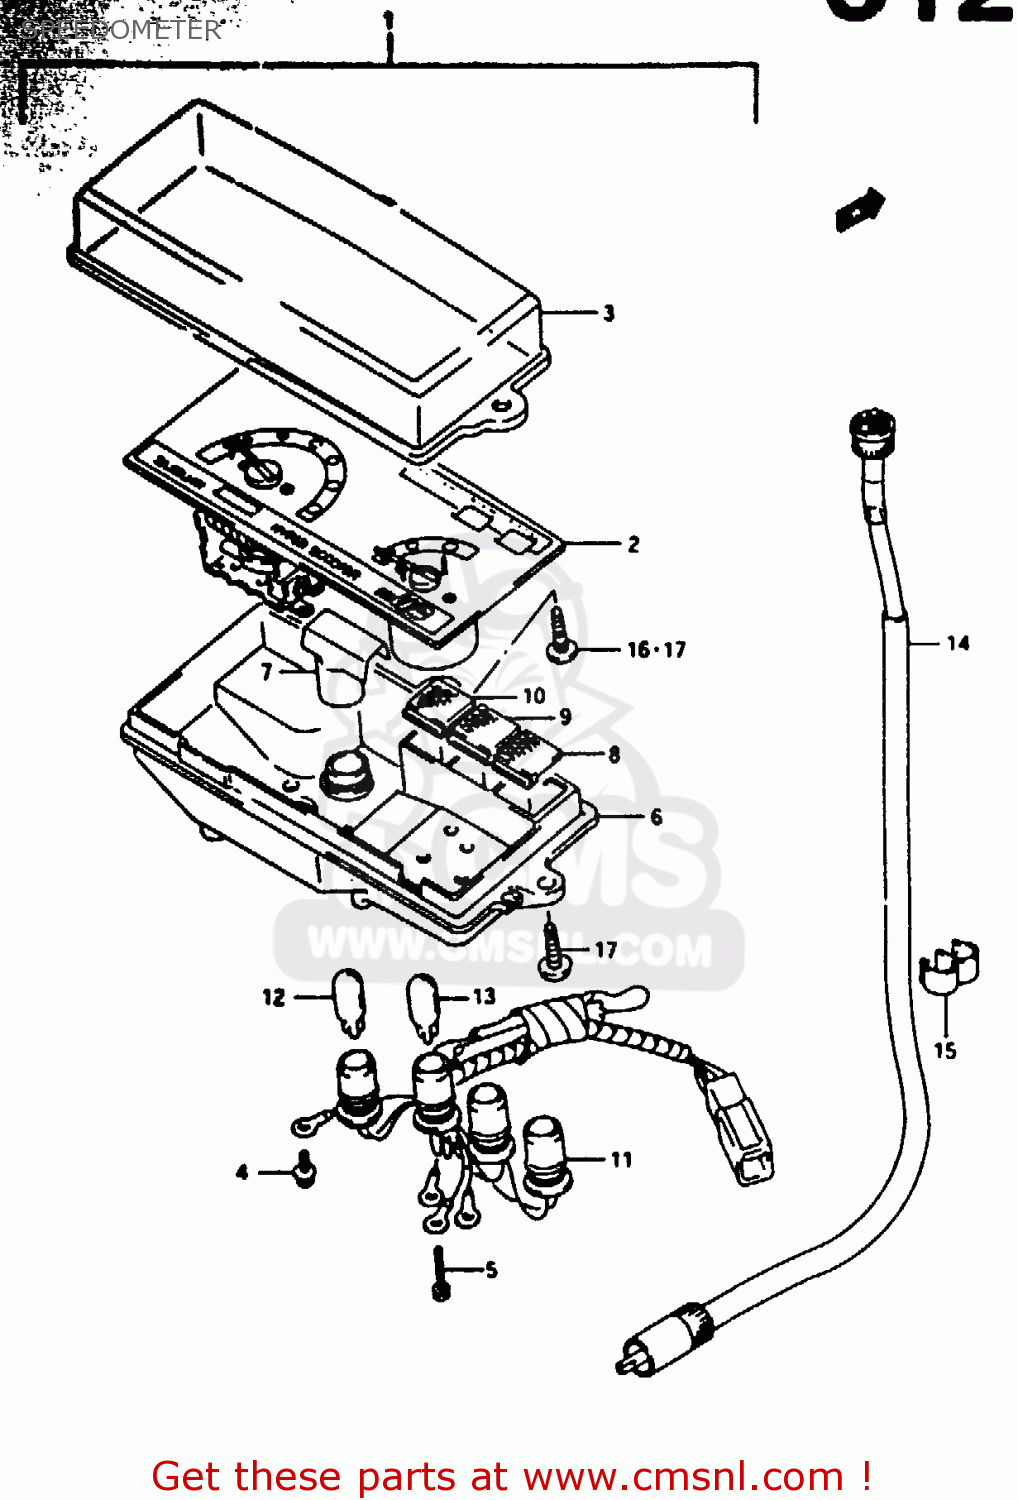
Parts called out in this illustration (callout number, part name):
1	SPEEDOMETER ASSY (KILO)
2	METER, SPEED (KILO)
3	HOOD,METER
4	SCREW
5	SCREW(3X22)
6	CASE, METER
7	SHADE
8	LENS
9	LENS,PILOT
10	LENS,PILOT
11	SOCKET
12	BULB(12V3.4W,T10)
13	BULB(12V1.7W,T10,WB121)
14	CABLE ASSY,SPEEDOMETER
15	CLAMP
16	SCREW
17	SCREW
